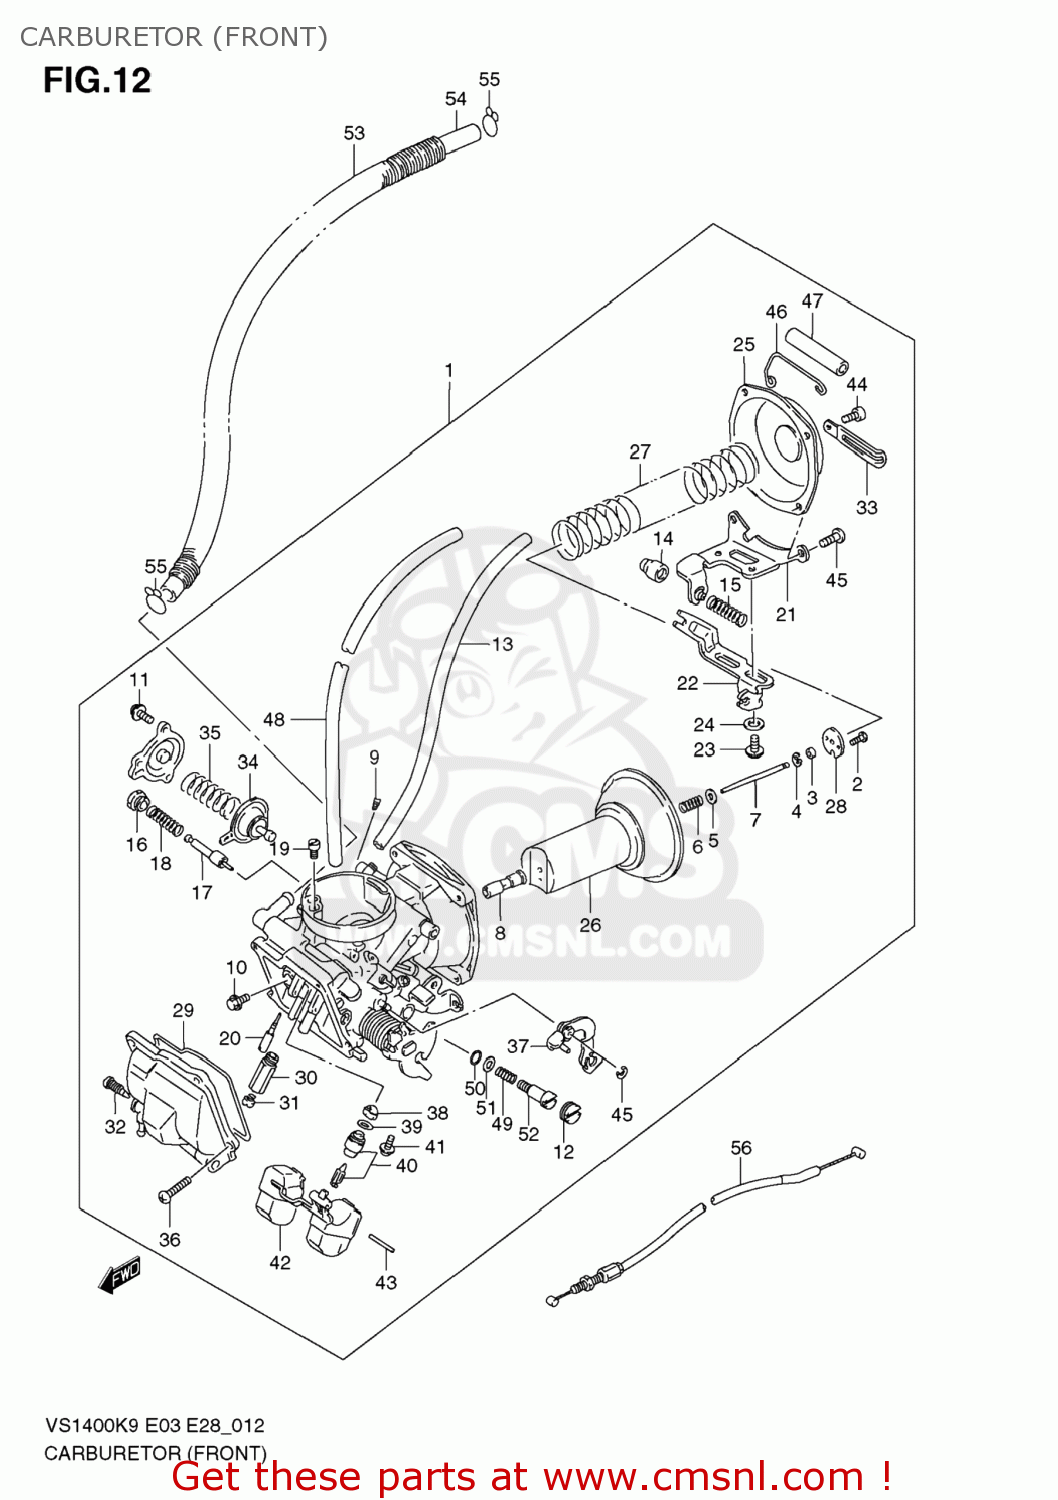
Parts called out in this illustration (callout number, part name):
1	CARBURETOR ASSY,FR
2	SCREW
3	RING
4	CLIP
5	WASHER
6	SPRING
7	NEEDLE,JET
8	JET,NEEDLE(O-9M)
9	JET,PILOT AIR,1.4
10	SCREW
11	SCREW
12	PLUG
13	HOSE
14	CAP
15	SPRING
16	HOLDER,GUIDE
17	PLUNGER
18	SPRING
19	JET,PILOT(70)
20	JET,PILOT(50)
21	BRACKET
22	PLATE
23	SCREW
24	WASHER
25	COVER,DIAPHRAGM
26	DIAPHRAGM,CARBURETOR
27	SPRING,DIAPHRAGM
28	PLATE
29	O RING,FLOAT CHAMBER
30	HOLDER,MAIN JET
31	JET,MAIN(125)
32	SCREW,DRAIN
33	CLAMP(L:45)
34	DIAPHRAGM ASSY
35	SPRING
36	SCREW
37	LEVER ASSY
38	FILTER
39	O RING,NEEDLE VALVE SEAT
40	VALVE ASSY,NEEDLE
41	SCREW
42	FLOAT
43	PIN,FLOAT
44	SCREW
45	E RING
46	CLIP
47	HOSE(6X10X600)
48	HOSE ASSY
49	SPRING
50	O RING,PILOT AIR SCREW
51	WASHER
52	SCREW,PILOT
53	SHIELD,FUEL HOSE HEATER
54	HOSE
55	CLIP
56	CABLE,IDLE SYNCRO
